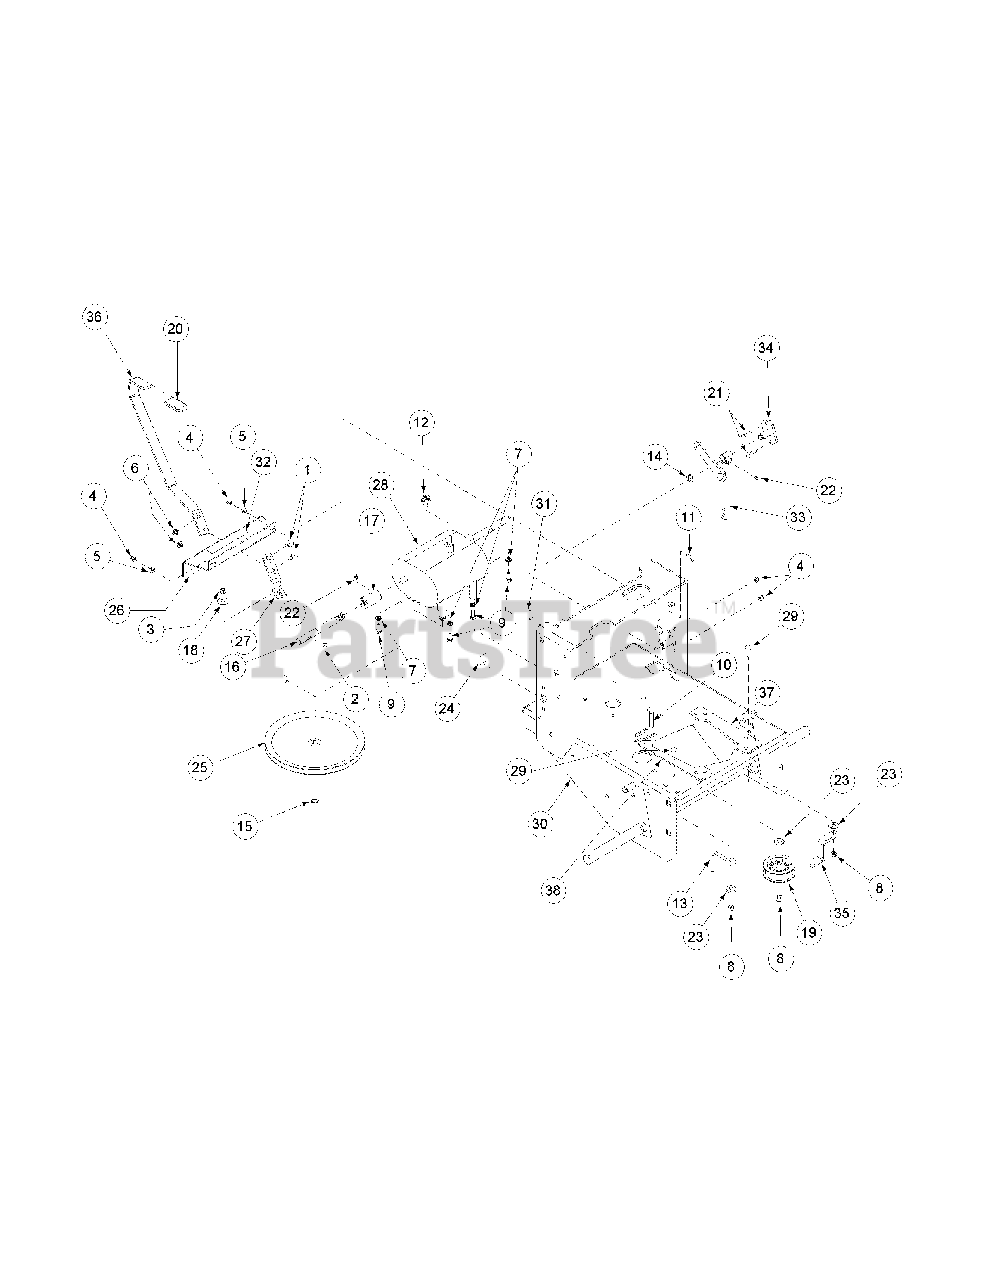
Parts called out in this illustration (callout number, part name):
1	Carriage Bolt, 5/16-18 x 1
2	Woodruff Key, 3/16 x 3/4
3	Jam Nut, Insert Lock, 3/8-24
4	Lock Nut, Nylon Insert, 1/4-20
5	Flat Washer, 1/4 Zinc
6	Nut, 5/16-18 Nylock
7	Lock Washer, 5/16 Zinc
8	Lock Nut, Nylon Insert, 3/8-16
9	Hex Cap Screw, 5/16-18 x 3/4
10	Carriage Bolt, 3/8-16 x2
11	Carriage Bolt, 1/4-20 x .750
12	Switch, WB Transmission
13	Drive Belt Guide
14	E-Ring, 5/8
15	External Retainer Ring
16	Jackshaft w/ Heavy Spline
17	Coupling w/Heavy Spline
18	Bell Washer, .39 ID x 1.13 OD x .062
19	Flat Idler Pulley w/Adapter
20	Grip, .250 x 1 x 3-1/2, Yellow
21	Carriage Bolt, 1/4-20 x 1.00
22	Grease Fitting, 1/4-28 x 3/16
23	Idler Washer
24	Decal "Made In America
25	Transmission Pulley
27	Shift Arm
28	Transmission, 5 Speed
29	Carriage Screw, 3/8-16 x 1.25
30	Engine Deck Assembly
31	Label, Warning, Open Belt Drive
32	Label, Mower Instruction
33	Clutch, Bellecrank Weldment
34	Bellecrank Pivot, Weldment
35	Engine Belt Guide
37	Engine Spacer, LH
38	Engine Spacer, RH
